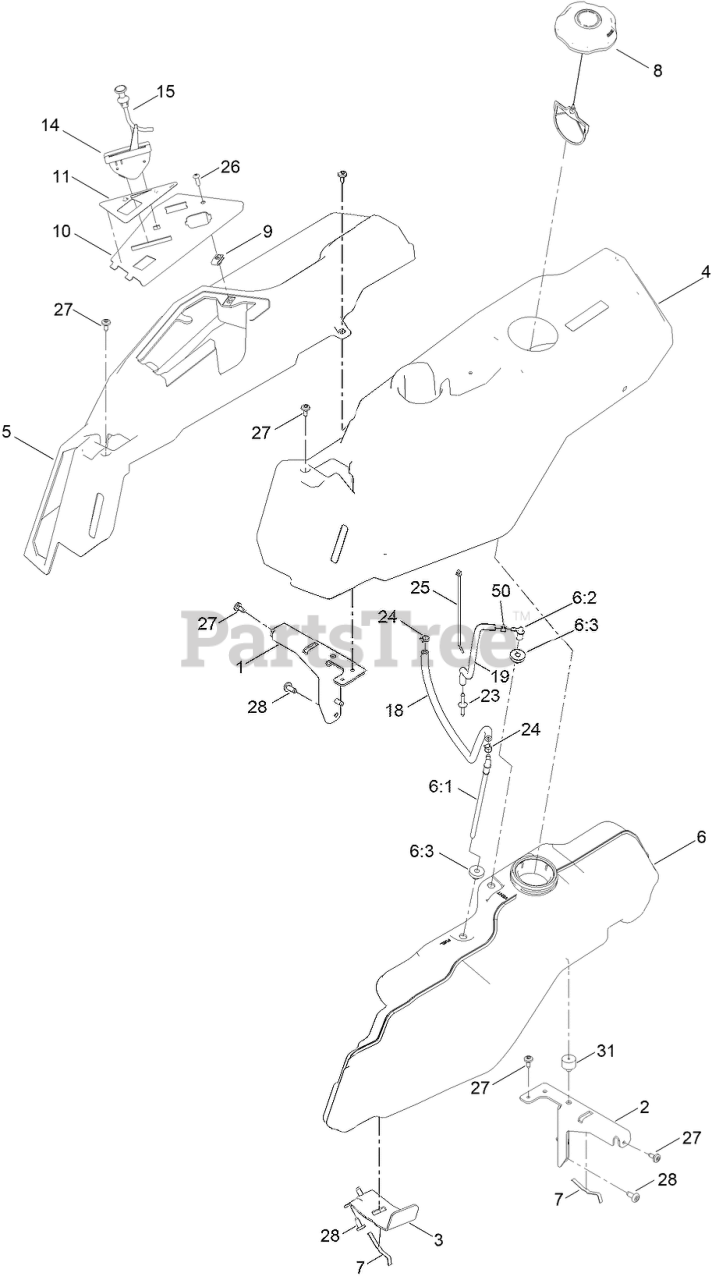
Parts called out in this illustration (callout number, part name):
1	SUPPORT-POD, RH
2	SUPPORT-POD, LH
3	SUPPORT-TANK, FUEL
4	POD-LH
5	POD-RH
6	TANK-FUEL ASM
6:1	CONNECTOR-ELBOW, 90 DEG
6:2	FITTING-ELBOW 90
6:3	BUSHING
7	SPRING
8	CAP-FUEL, RATCHETING
10	PANEL - CONTROL
11	DECAL-PANEL CONTROL
14	CABLE-THROTTLE
15	CABLE-CHOKE
18	HOSE-FUEL
19	HOSE-FUEL
23	ADAPTER ORIFICE
24	CLAMP-HOSE
25	TIE-CABLE
26	SCREW-PRH
27	SCREW-SHOULDER
31	BUMPER-GROMMET
50	CLAMP-HOSE
